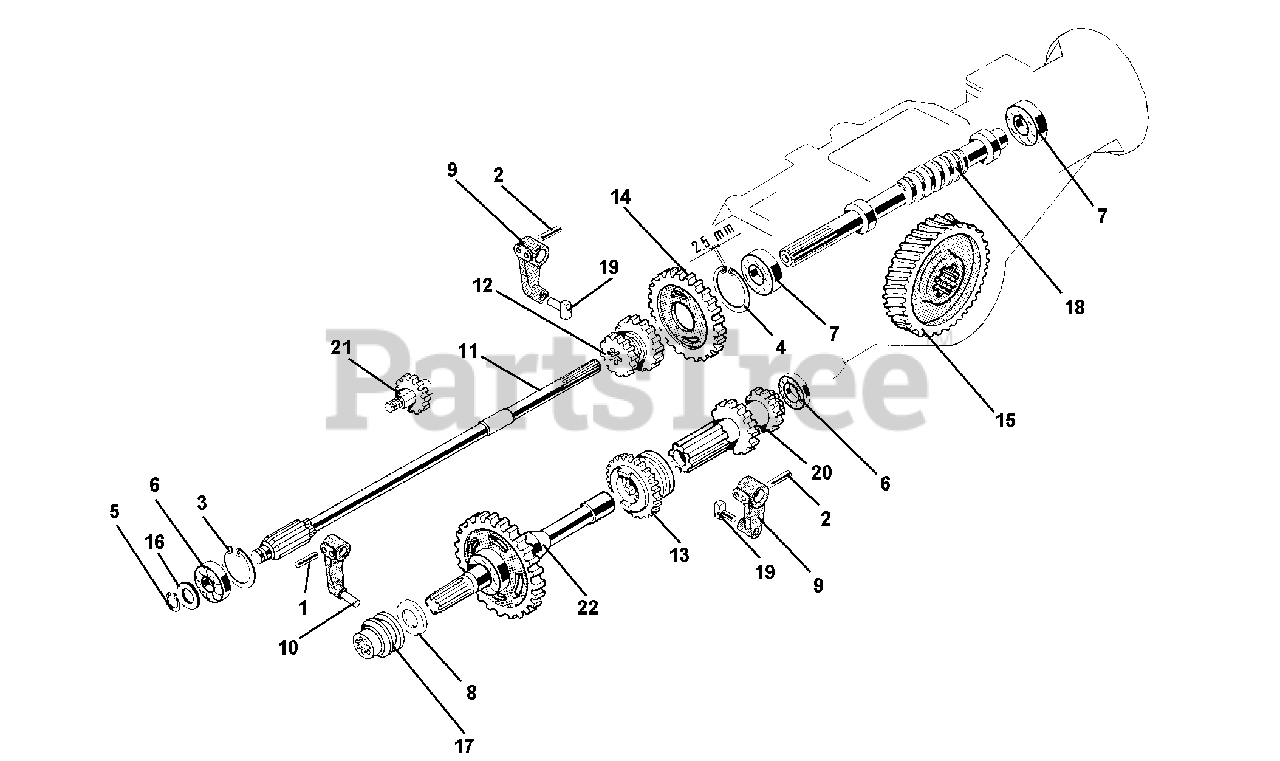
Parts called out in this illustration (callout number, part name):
1	LOCKING PIN 4 X 20 SPIRAL
2	LOCKING PIN 4 X 24 SPIRAL
3	INSIDE CIRCLIP DIAM. 35
4	INSIDE CIRCLIP DIAM. 52
7	BEARING SKF 25 X 52 X 15 6205
8	SEAL, OIL 20 X 35 X 7 STANDARD
9	LEVER, SPEED CHG SLDG GR
10	SLIDE LEVER
11	CLUTCH SHAFT FOR REVERSER
12	DOUBLE SLIDER
13	REVERSER SLIDER
14	WHEELS FIRST SPEED
15	GEAR Z 49, LH MOTOR MOWER
16	WASHER 15.1 X 25 X 2
20	SECOND GEAR
21	REVERSER PIN
22	P.T.O. SHAFT
